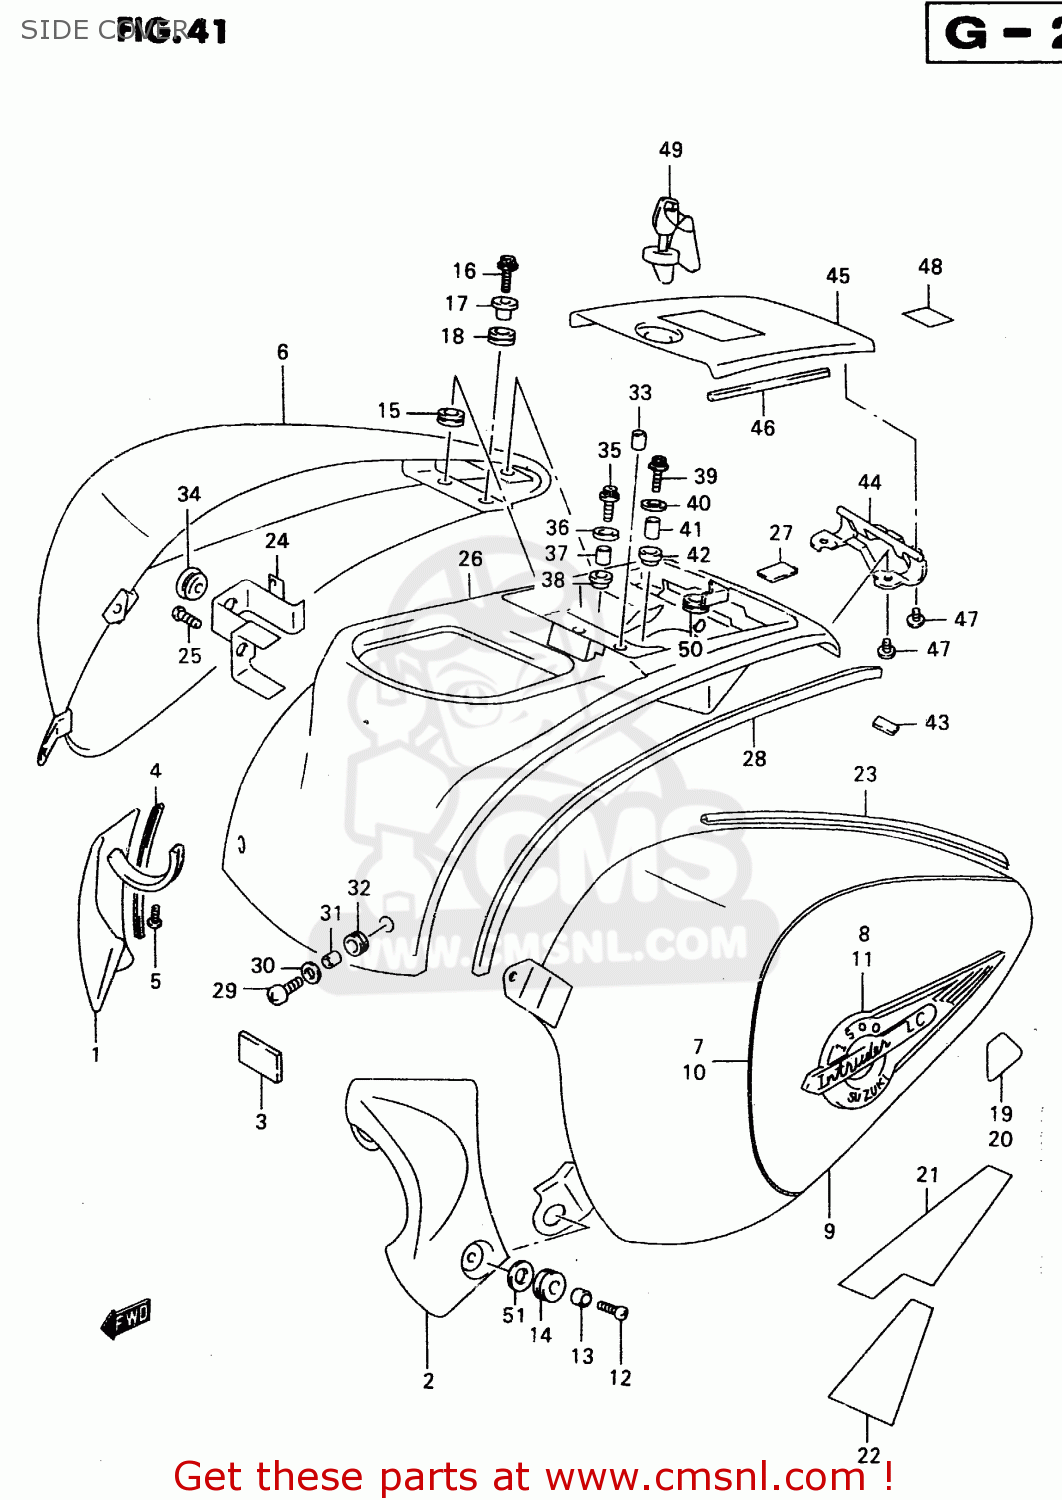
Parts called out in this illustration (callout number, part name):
1	COVER COMP,FRAME HEAD
2	COVER COMP,FRAME HEAD
3	CUSHION,METER COVER RE
4	MOLDING,FRAME HEAD COVER
5	SCREW(6X20)
6	COVER ASSY,SIDE UPR,R
7	TAPE,SIDE COVER UPR,R
8	EMBLEM,TANK COVER,R
9	COVER ASSY,SIDE UPR,L
10	TAPE,SIDE COVER,UPPER
11	EMBLEM,TANK COVER,L
12	SCREW(6X16)
13	SPACER(6.5X9X7.2)
14	CUSHION
15	CUSHION,SIDE UP METER & FRAME
16	BOLT
17	WASHER,SIDE UPR COVER
18	CUSHION,SIDE UPR COVER
19	TAPE,SIDE COVER UPR,R
20	TAPE,SIDE COVER UPR,L
21	CUSHION,SIDE UPR COVER,R
22	CUSHION,SIDE UPR COVER,R
23	MOLDING,SIDE UPPER COVER
24	BRACKET,SIDE UPPER COVER
25	SCREW
26	COVER,METER & FUEL INLET
27	TAPE,METER COVER
28	MOLDING,METER COVER
29	SCREW(6X16)
30	WASHER(6.5X18X1.5)
31	SPACER(6.5X9X5.7)
32	CUSHION
33	CUSHION
34	CUSHION
35	BOLT,OIL PAN
36	WASHER(6.5X18X1.6)
37	SPACER(6.5X9X11)
38	CUSHION,METER COVER
39	BOLT MAGNETO S
40	WASHER(6.5X18X1.6)
41	SPACER(6.5X9X5.7)
42	CUSHION
43	CUSHION,METER COVER RE
44	HINGE COMP,FUEL LID
45	LID,FUEL INLET
46	CUSHION,FUEL LID
47	SCREW 6X12
48	TAPE,FUEL LID
49	LOCK SET,COVER
50	CUSHION,RR,L
51	WASHER
